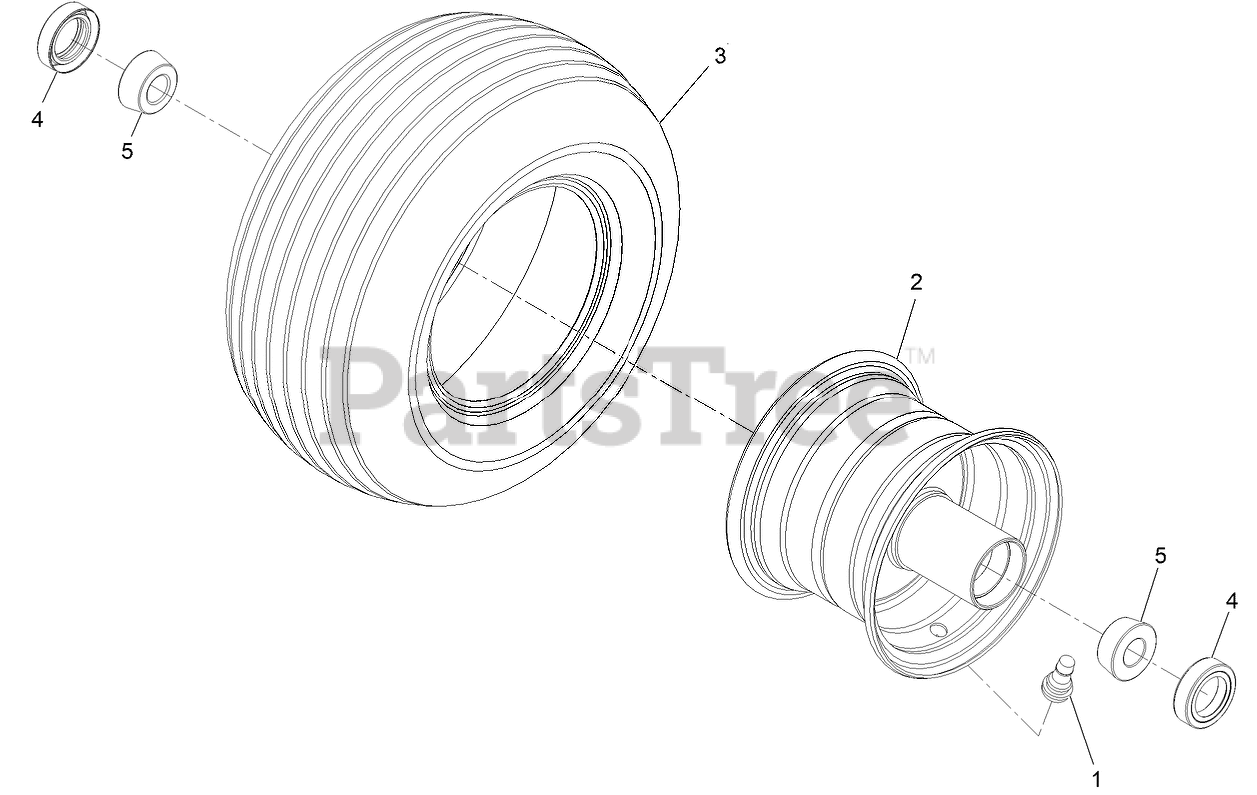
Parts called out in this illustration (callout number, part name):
1	VALVE
2	Rim-6 X 4.5
3	Tire-Rib
4	SEAL-CASTER
5	BEARING-CONE, TAPERED ROLLER
